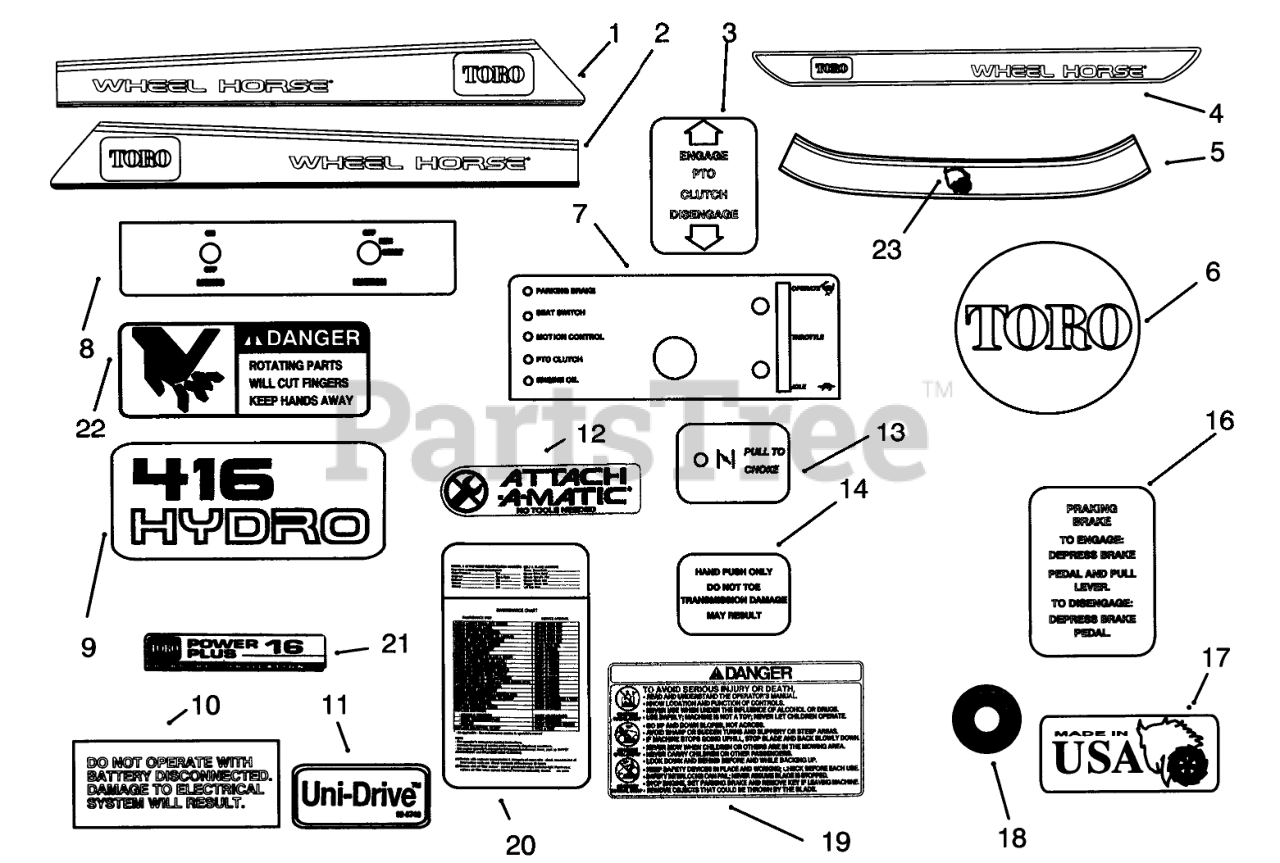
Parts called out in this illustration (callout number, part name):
1	DECAL - RH HOOD TOP
2	DECAL - LH HOOD TOP
3	DECAL PTO CLUTCH
4	DECAL - REAR FENDER
5	DECAL-FRONT HOOD, TOP
6	NAME-PLATE TORO LOGO
7	DECAL-DASH
8	DECAL-BACK PLATE
9	DECAL - MODEL 416-H
10	DECAL ELECT SYSTEM
11	Decal-Unidrive
12	DECAL-ATTACH A-MATIC
13	DECAL-CHOKE
14	DECAL-DO NOT TOW
16	DECAL-PARKING BRAKE
17	DECAL - USA
18	Decal-Air Cleaner
19	DECAL - DANGER
20	Decal-Maintenance
21	DECAL-PWR PLUS 16 PL
22	DECAL - DANGER
23	PLATE - LOGO WHL HORSE
